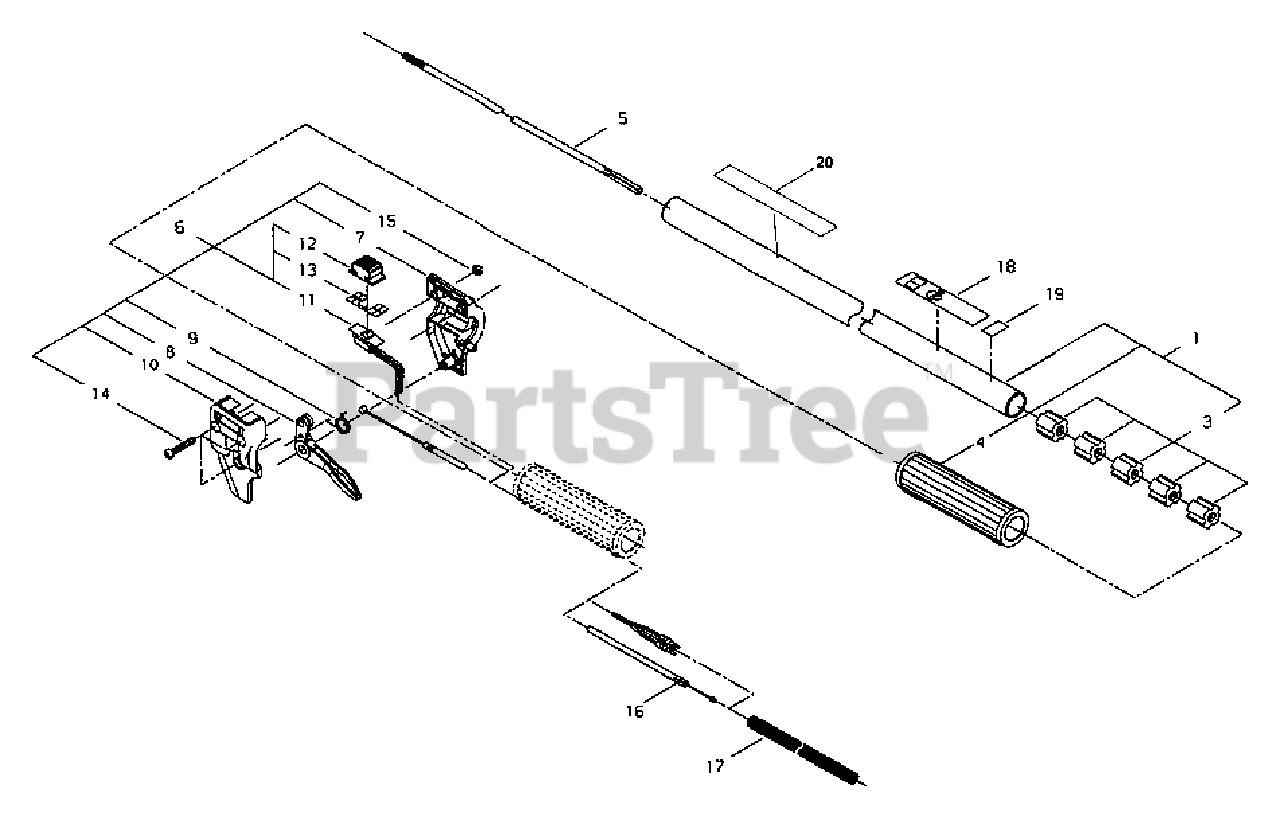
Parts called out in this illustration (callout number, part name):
1	MAIN PIPE ASSY
3	BUSHING
4	GRIP
5	DRIVESHAFT - FLEXIBLE
6	THROTTLE LEVER ASSY
7	BRACKET - RIGHT
8	TRIGGER, THROTTLE
9	SPRING, TRIGGER
10	BRACKET - LEFT
11	SWITCH
12	KNOB
13	PLATE, SWITCH
14	SCREW - 5X30
15	NUT - 5
16	CABLE, THROTTLE
17	TUBE
18	LABEL - CAUTION
19	LABEL - INSTRUCTION
20	LABEL - OUTER TUBE
